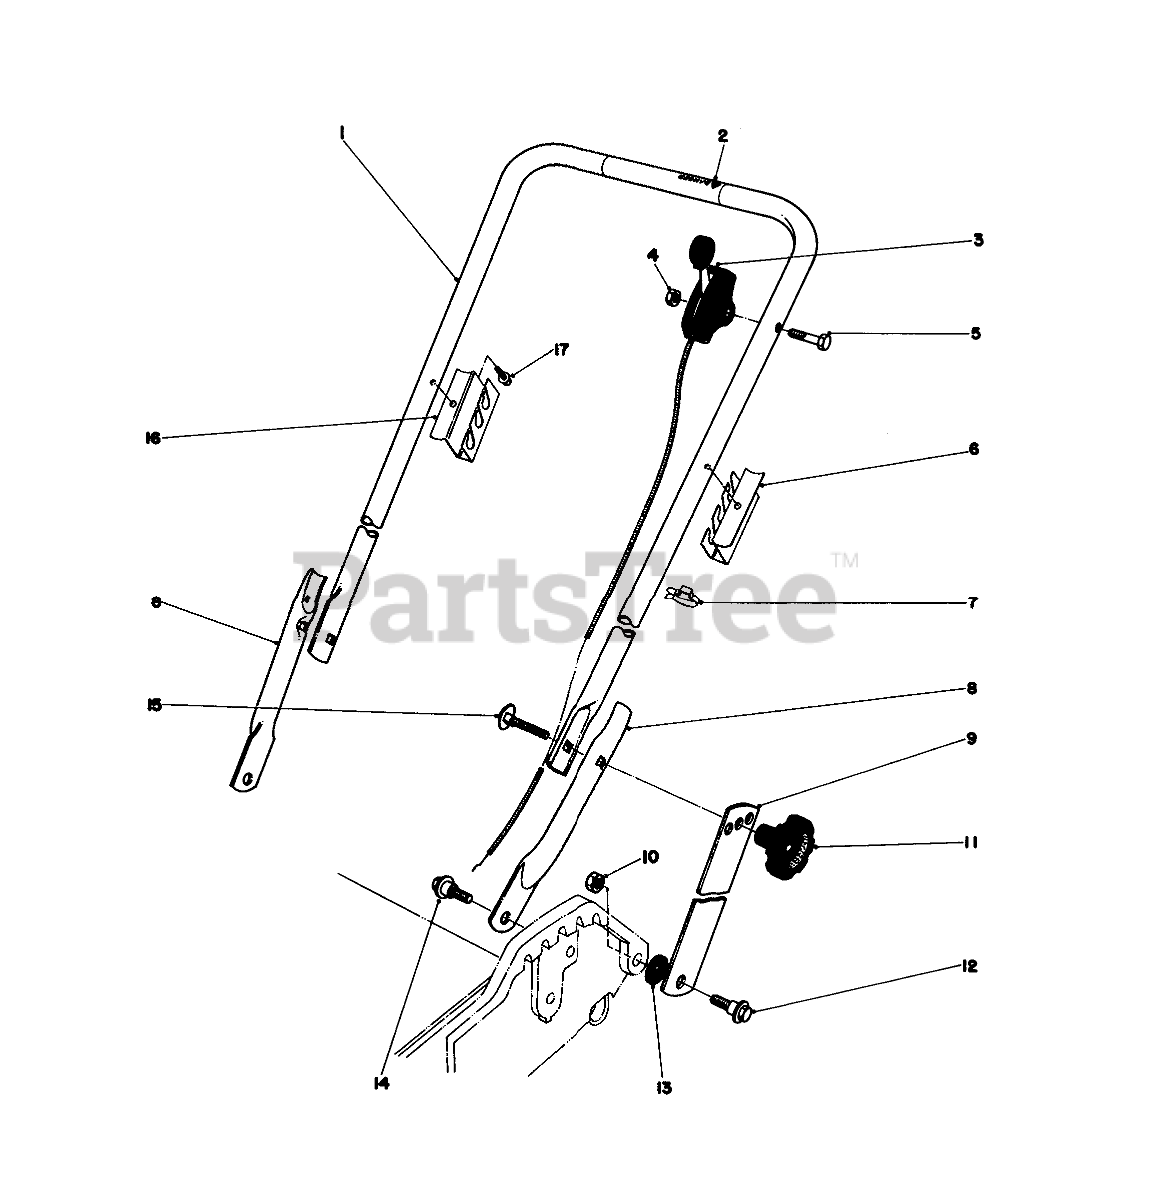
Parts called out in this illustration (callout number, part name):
1	Handle-Upper
2	Decal
3	Throttle Control
4	NUT-LOCK
5	SCREW-HH
6	SUPPORT BAG LH
7	BOWDEN CLIP
8	Hand-Lower
9	18" HANDLE LATCH
10	Nut
12	SCREW-SHOULDER
13	SPACER
14	SCREW-SHOULDER
15	SCREW-HANDLE
16	SUPPORT BAG RH
17	SCREW-HWHTF
